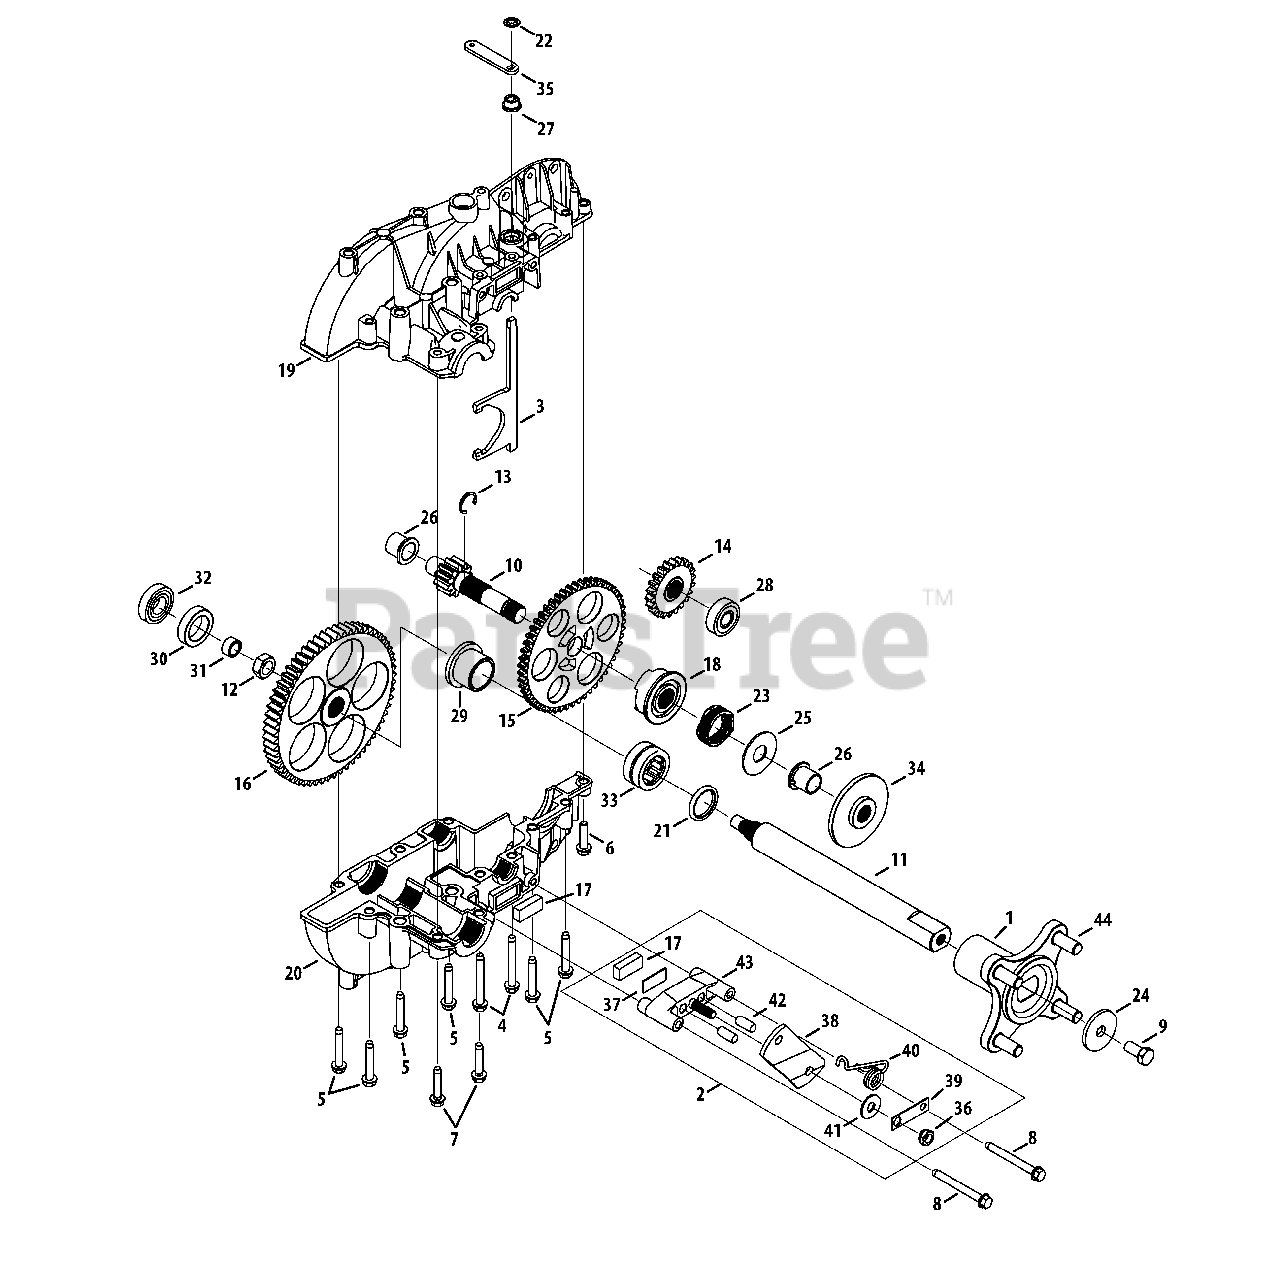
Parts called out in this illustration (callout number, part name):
1	Wheel Hub Assembly
2	Brake Ass’y, Yoke, RH
2	Brake Ass’y, Yoke, LH
3	Neutral Actuator
4	Screw, 1/4-20 x 2.00
5	Hex Washer Screw, 1/4-20 x 1.500
6	Hex Washer Screw, 1/4-20 x 1.000
7	Hex Washer Screw, 1/4-20 x 1.250
8	Hex Washer Screw, 1/4-20 x 2.375
9	Hex Cap Screw, 3/8-16 x .75
10	Electric Output Shaft, 11T
11	Axle Shaft
12	Jamlock Nut, 1/2-20
13	Retainer Ring, 7MM
14	Spur Gear, 22T
15	Spur Gear, 53T
16	Spur Gear, 61T
17	Brake Pad
18	Clutch Collor, U-Turn
19	Axle Housing
20	Axle Housing
21	Seal, 1.00 x 1.25 x .125
22	Push Nut, 1/4 x 17/32
23	Spring, 1.00 x 1.375 x .400
24	Flat Washer, .39 x 1.5 x .134
25	Flat Washer, 1.595 x .635 x .062
26	Flange Bearing, 5/8 x 3/4 x 3/4
27	Flange Slotted Bearing
28	Ball Bearing
29	Flange Bearing, 1.004 x 1.25
30	Thrust Bearing
31	Sleeve Bearing
32	Ball Bearing, .625 x 1.375 x 11/32
33	Bearing, 1.00 x 1.50 x .750
34	Brake Disc
35	Lever Plate
36	Hex Lock Nut, 5/16-24
37	Puck Plate
38	Arm, Brake Actuator - RH Brake
38	Arm, Brake Actuator - LH Brake
39	Anti-Rotation Brkt.
40	Torsion Spring, .75 OD x 3 Coils, RH
40	Torsion Spring, .75 OD x 3 Coils, LH
41	Flat Washer, .343 x .880 x .062
42	Brake Actuating Pin
43	Brake Yoke
44	Stud, rib Neck, 7/16-14 x 1.6
